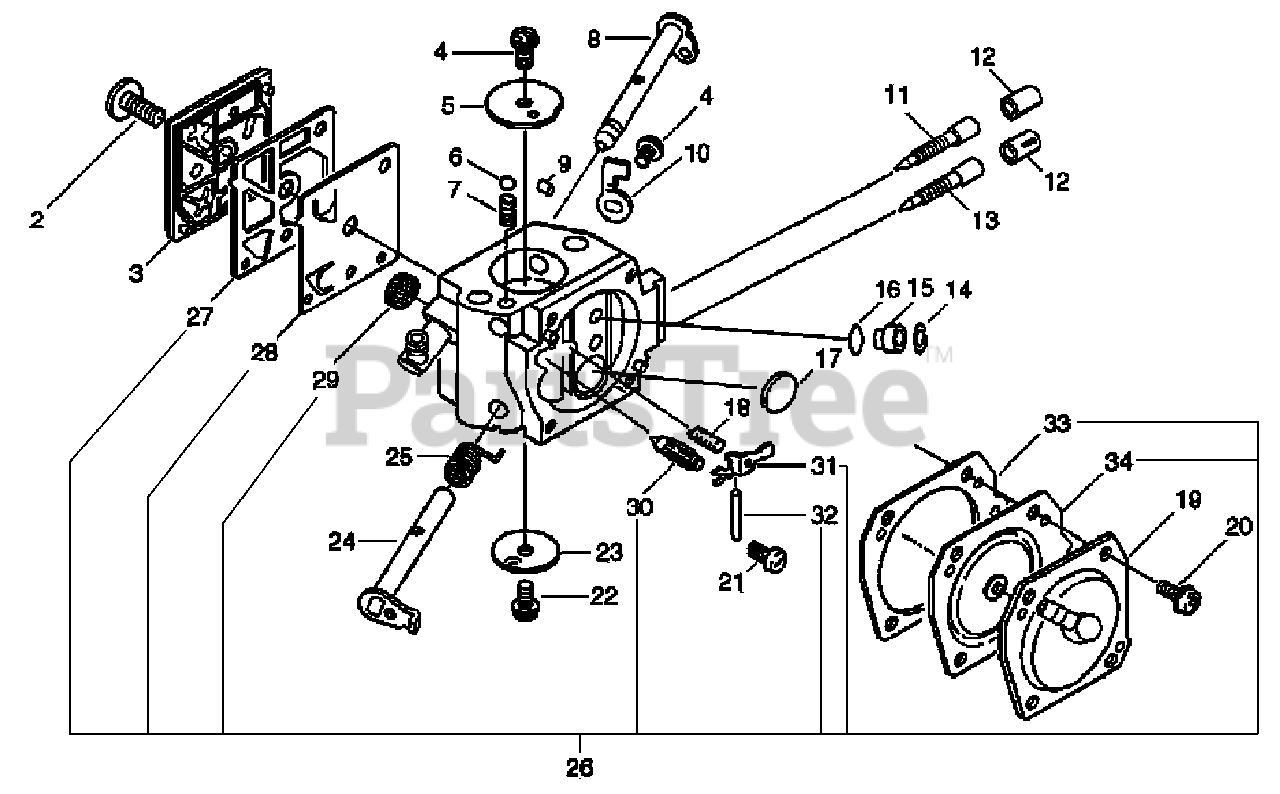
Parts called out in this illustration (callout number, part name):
1	CARBURETOR
3	COVER, FUEL PUMP
5	VALVE, CHOKE
6	BALL, CHOKE FRICTION
8	SHAFT, CHOKE
9	PLUG, FRICTION
10	STOP, THROTTLE
11	NEEDLE, HIGH SPEED
12	CAP, LIMITER
13	NEEDLE, MIXTURE
14	RING, RETAINING
15	JET
16	O-RING
17	PLUG, WELCH
18	SPRING, METERING LEVER
19	COVER, METERING DIAPHRAGM
21	SCREW, METERING LEVER PIN
23	VALVE, THROTTLE
24	SHAFT, THROTTLE
25	SPRING, THROTTLE RETURN
26	REPAIR KIT
27	GASKET, FUEL PUMP
28	DIAPHRAGM, PUMP
30	VALVE, INLET NEEDLE
31	LEVER, METERING
32	PIN, METERING LEVER
33	GASKET, METERING
34	DIAPHRAGM ASSY
